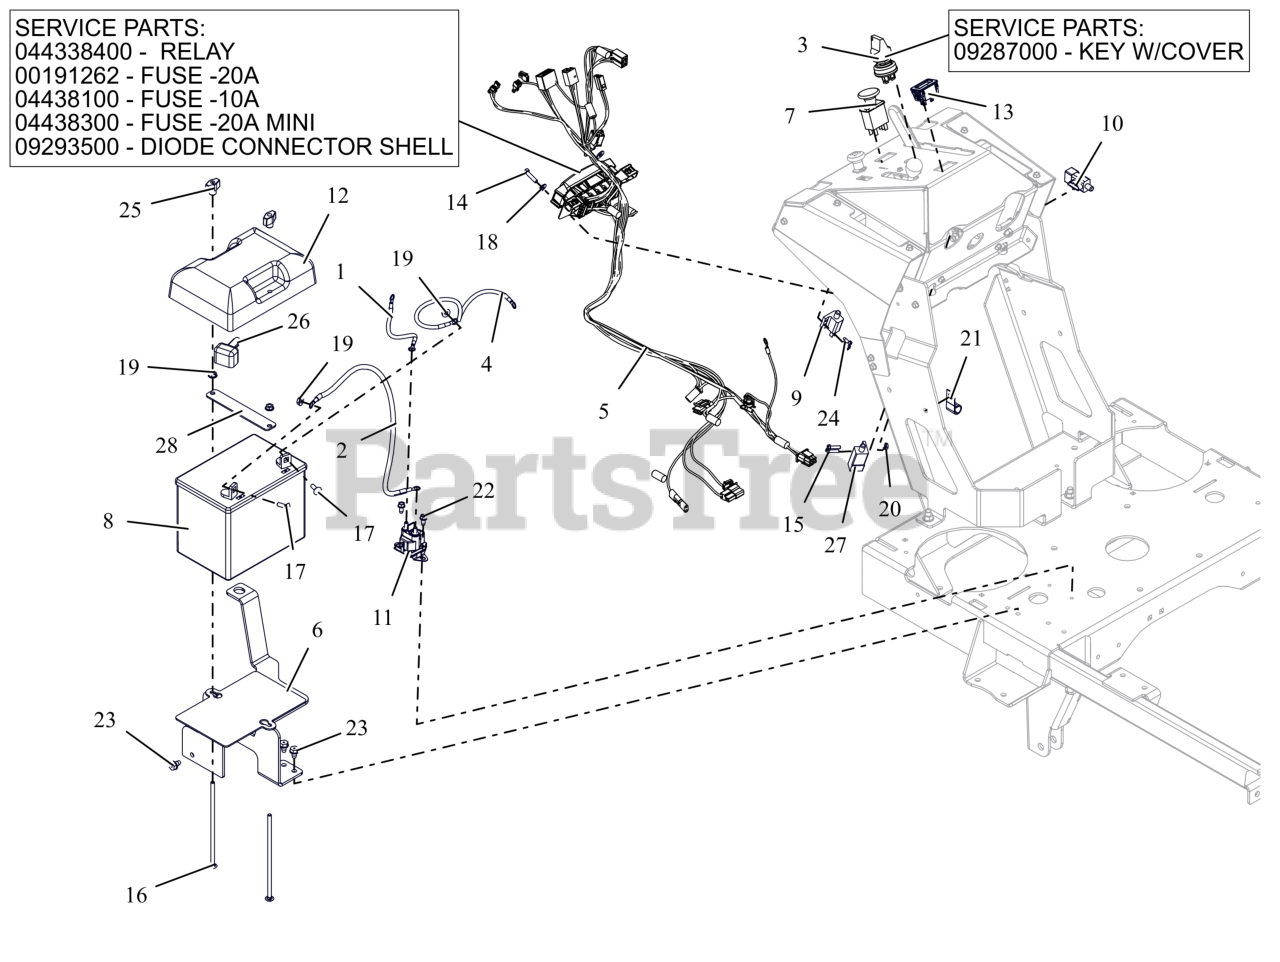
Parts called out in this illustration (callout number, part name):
1	CABLE-POSITIVE BATTERY 9.00"
2	CABLE - START 22.00"
3	SWITCH, IGNITION
3	KEY, W/ SHIELD
4	CBL,NEGATIVE BATTERY 20.00
5	HARNESS, 36-60 PRO-WALK
5	FUSE, 20 AMP BLADE S/O
5	FUSE,10 AMP MINI-ATC
5	FUSE,20 AMP MINI ATC
5	DIODE, CONNECTOR SHELL
6	WLDMT, BATTERY TRAY 48"-60"
7	SWITCH, CLUTCH
8	BATTERY, 300 CCA 10U1L
9	SWITCH- SINGLE POLE N.O.
10	SWITCH, SNAP IN - N.O./N.O.
11	SOLENOID, STARTER (SEALED)
12	COVER, BATTERY
13	HOUR METER
14	BLT, HEX M6-1.0 X 25 G8.8 ZCC
15	BLT, HWH #10-24X.75 ZCC
16	BLT,RHSN .25-20X7.00 G2 ZCC
17	BLT, RHSN .25-20X.750 G5 ZCC
18	WSHR,FLT .281X.625X.065 ZCC
19	NUT-SPNLK-FLG .25-20 ZC120
20	NUT, HEX .250-20 GR5 ZCC
22	SCR-TAP .25-20X.50 HWH ZCC
23	SCR,TAP .312-18X.50 HWH TR ZCC
24	SCR,TAP #10-24X.50 HWH TR ZCC
25	KNOB, WING - .25-20 UNC
26	INSULATOR
27	SWITCH,INTERLOCK
28	STRAP, BATTERY
